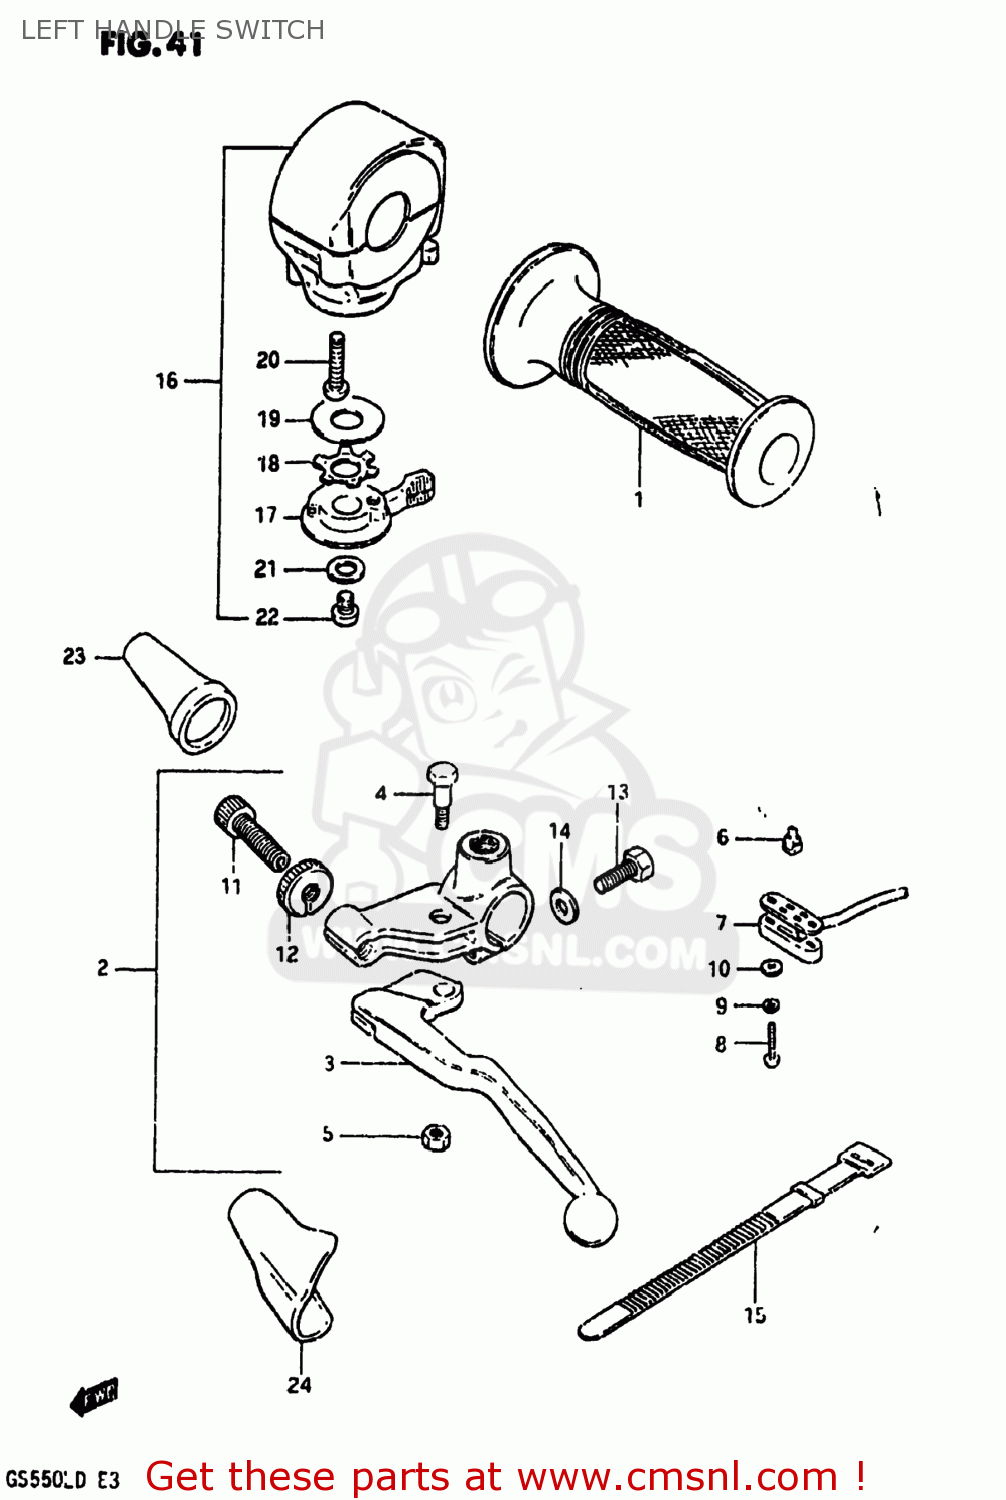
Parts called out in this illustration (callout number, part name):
1	GRIP
2	LEVER ASSEMBLY
3	LEVER,CLUTCH
4	BOLT,LEVER
5	NUT 6MM
6	CONTACT,SWITCH
7	COVER,FR BK TERMINAL BASE
8	SCREW
9	LOCK WASHER
10	WASHER
11	ADJUSTER,CABLE
12	NUT,CABLE ADJUSTER
13	BOLT,CLUTCH LEVER HOLDER
14	SPACER
15	CLAMP(L:120)
16	SWITCH ASSEMBLY,HANDLE,LEFT
17	LEVER,STARTER
18	WASHER
19	WASHER
20	SCREW
21	WASHER 6MM
22	SCREW
23	BOOT,CLUTCH CABLE
24	COVER,CLUTCH LEVER
